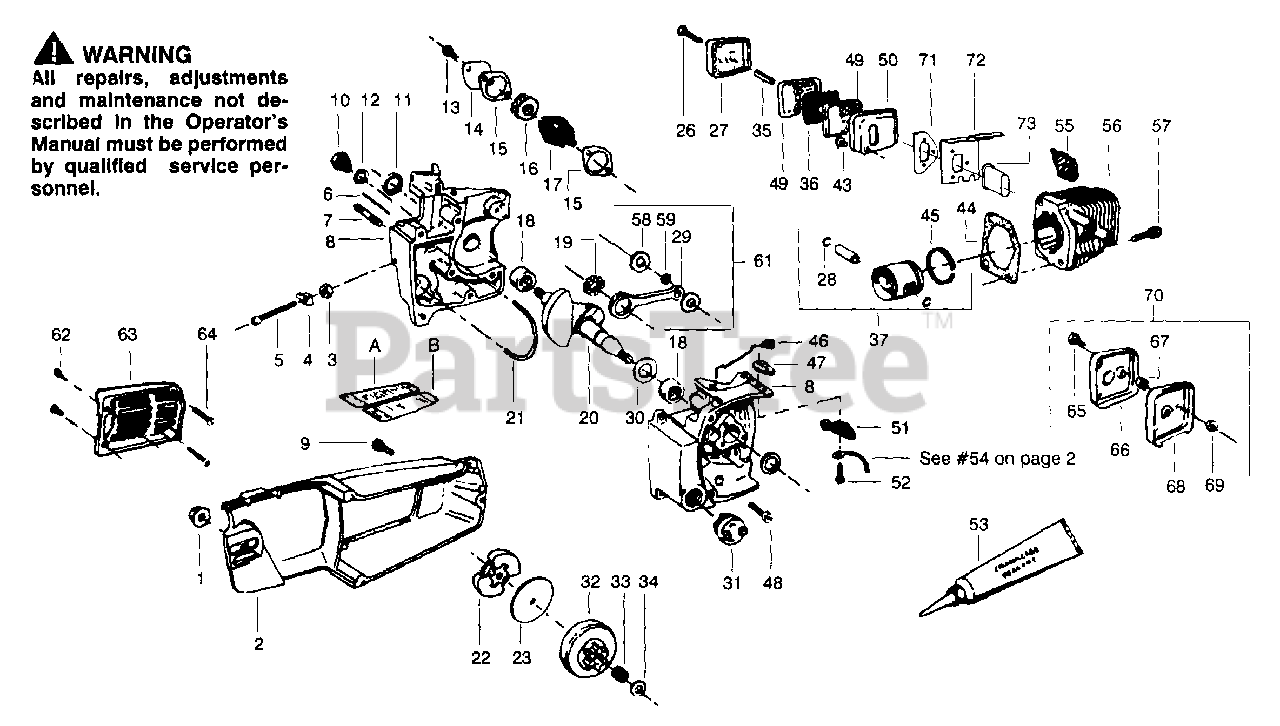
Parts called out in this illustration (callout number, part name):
1	Bar Mounting Nut
2	Bar Clamp
3	Lock Nut
4	Bar Adjust Pin
6	Oil Tank Vent Pin
7	Bar Mounting Stud
8	Crankcase Ass'y
10	Check Valve Kit
11	Crankshaft Seal
12	Check Valve Gasket
14	Metering Body Cover
15	Metering Body Gasket
16	Oil Filter
17	Oil Pump Ass'y
18	Crankshaft Bearing
19	Roller Bearing
20	Crankshaft
21	Oil Discharge Line
22	Clutch Ass'y Kit
23	Clutch Washer Kit (Outside)
27	Muffler Cover
28	Piston Pin Retainer
29	Connecting Rod-1800; 2000
30	Thrust Washer
31	Oil Cap Ass'y
31	T 1 & T 2
31	T 3 & T 4
32	Clutch Drum
33	Clutch Bearing
34	Clutch Spacer (Inside)
36	Spark Arrestor Screen
37	Piston
37	1800-T 1 & T 2
37	2000 - T 1, 2 & 3, & Model 1800-T 3 & 4
44	Cylinder Gasket
45	Piston Ring
45	Model 1800,
45	Model 2000
46	Switch Knob Ass'y
47	Ramp Switch
49	Muffler Baffle
50	Muffler Body
51	Switch Clamp
53	Crankcase Sealant
55	Spark Plug
56	Cylinder
58	Washer - 2000
59	Bearing Rod (Top
61	Connecting Rod Ass'y Kit
62	Screw-T 2
63	Muffler Shield
66	Heat Shield
68	Muffler Cover
70	Heat Shield Kit
71	Gasket - Muffler - T 4
72	Muffler Back Plate - T 4
73	Port-Insulator - T 4
A	Instructions Decal-Rt Hand
B	Instruct Decal - Left Hand
